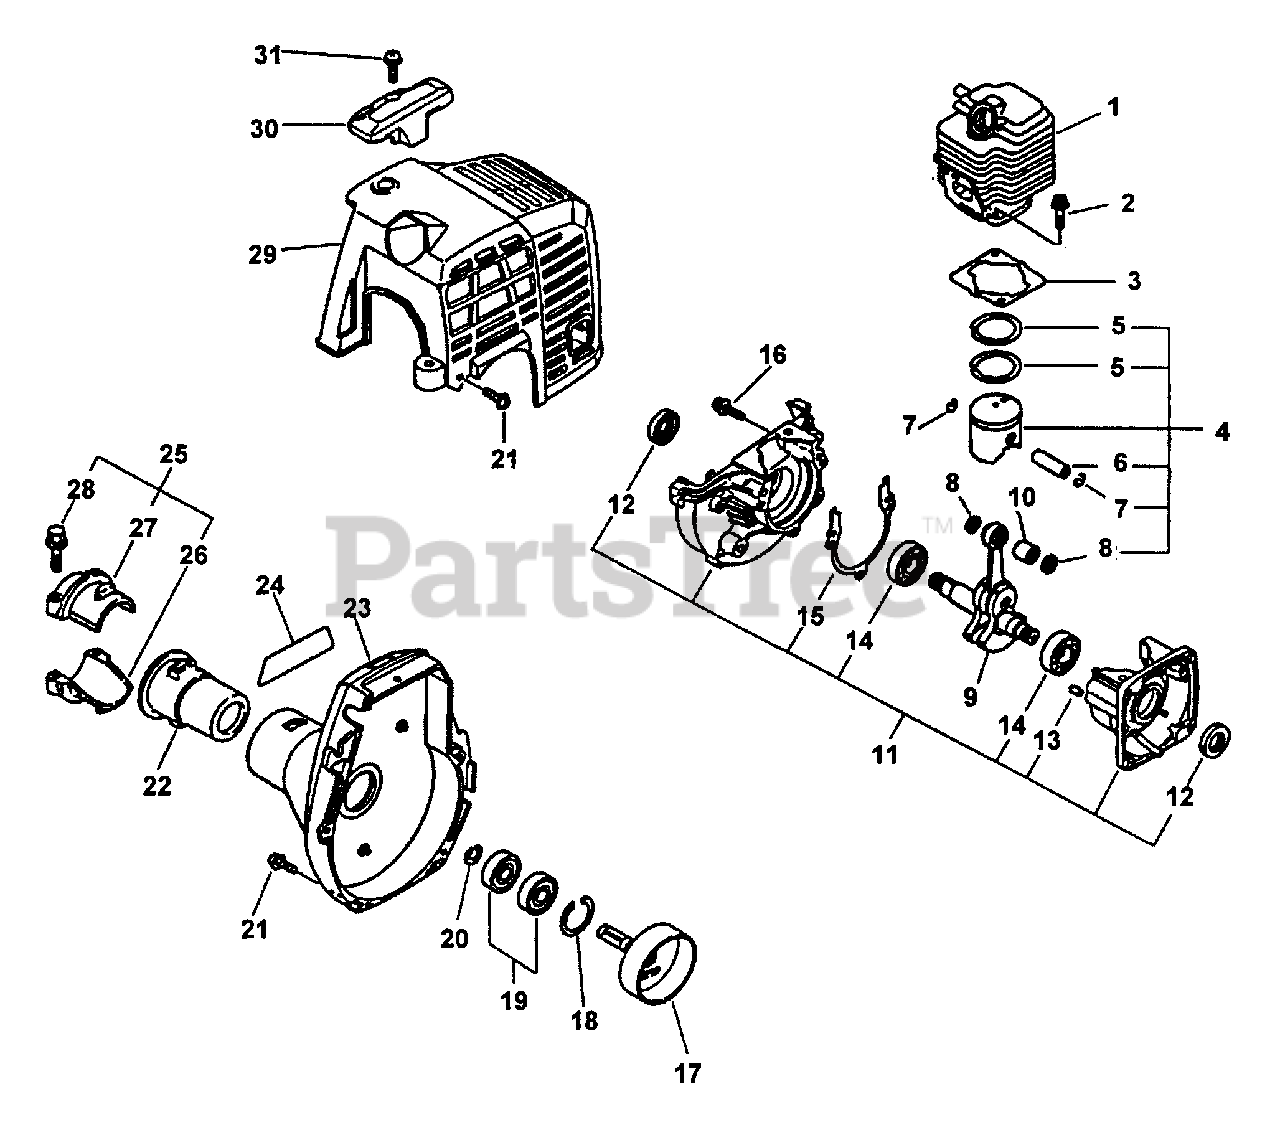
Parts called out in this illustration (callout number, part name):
1	CYLINDER
2	BOLT 5×22
3	GASKET, CYLINDER
4	PISTON KIT
5	RING, PISTON
6	PIN, PISTON 8
7	RING, SNAP
8	WASHER, THRUST
9	CRANKSHAFT ASSY
10	BEARING, NEEDLE
11	CRANKCASE KIT
12	SEAL, OIL 12
13	PIN, LOCATING 4
14	BEARING, BALL - 6201 C3
15	GASKET, CRANKCASE
16	BOLT 5×28
17	DRUM, CLUTCH
18	RING, SNAP 28
19	BEARING, BALL 6001
20	RING, RETAINING - 12
21	BOLT 4×16
22	CUSHION
22	CUSHION Ø25
23	FAN CASE ASSY
23	COVER ASSY, FAN
24	LABEL, PE-2400
25	HOLDER KIT
25	RETAINER KIT
26	HOLDER
26	HOLDER, MAIN PIPE - LOWER
27	HOLDER, MAIN PIPE - UPPER
28	BOLT - 5×25
29	COVER, ENGINE
30	GUARD, TOP
31	SCREW 5×16
